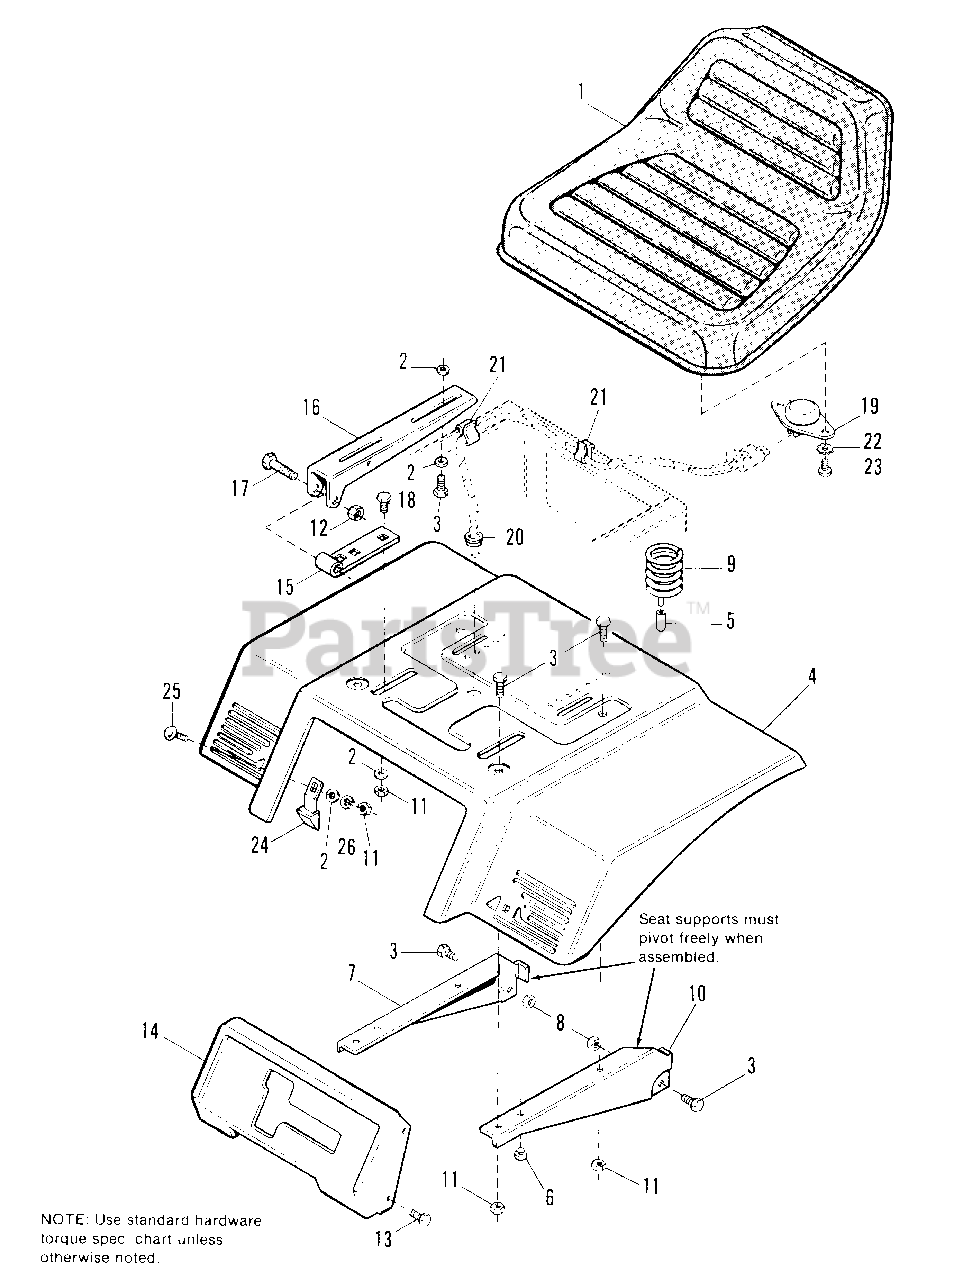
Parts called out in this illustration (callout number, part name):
2	WASHER, Plain, 5/16
3	CAPSCREW, Hex, 5/16-18 x 3/4
4	DECK, Seat
5	COVER, Wire
6	BUMPER, Plug
7	SUPPORT, Seat, R.H.
8	LOCKNUT, Hex, 5/16-18
9	SPRING, Seat
10	SUPPORT, Seat, L.H.
11	NUT, Hex, Full, 5/17-18
12	LOCKNUT, Hex, 3/8-16
13	SCREW, Hex, Taptite, 5/16-18 x 3/8
14	PANEL, Shift
15	HINGE, Lower
16	HINGE, Upper
17	CAPSCREW, Hex, 3/8-16 x 2
18	CAPSCREW, Hex, 5/16-18 x 1.0
19	SWITCH, Seat
20	BUSHING, Snap
22	LOCKWASHER, 1/4 Ext. Tooth
23	SCREW, Rd. Hd., 1/4-20 x 1/2
24	SEAT LATCH ASSY.
25	BOLT, Carriage, 5/16-18 x 3/4
26	LOCKWASHER, 5/16
